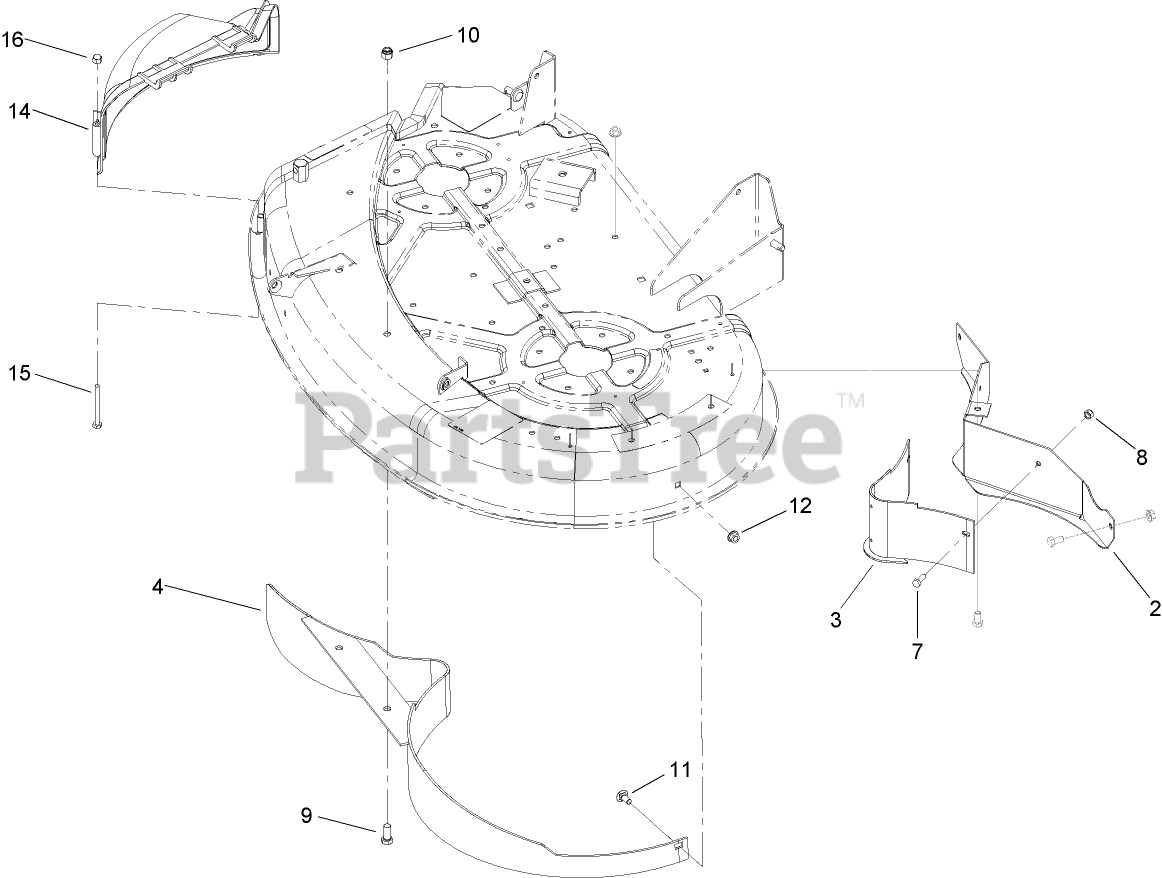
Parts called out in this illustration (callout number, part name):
2	BAFFLE-REAR
3	BAFFLE ASM
4	BAFFLE-38 INCH
7	SCREW-HH
8	NUT-LOCK, NI
9	SCREW-HH
10	NUT-LOCK, NI
11	BOLT-CARR
12	NUT-HF
14	COVER-DISCHARGE, DECK
15	SCREW-HH
16	NUT-CAP
